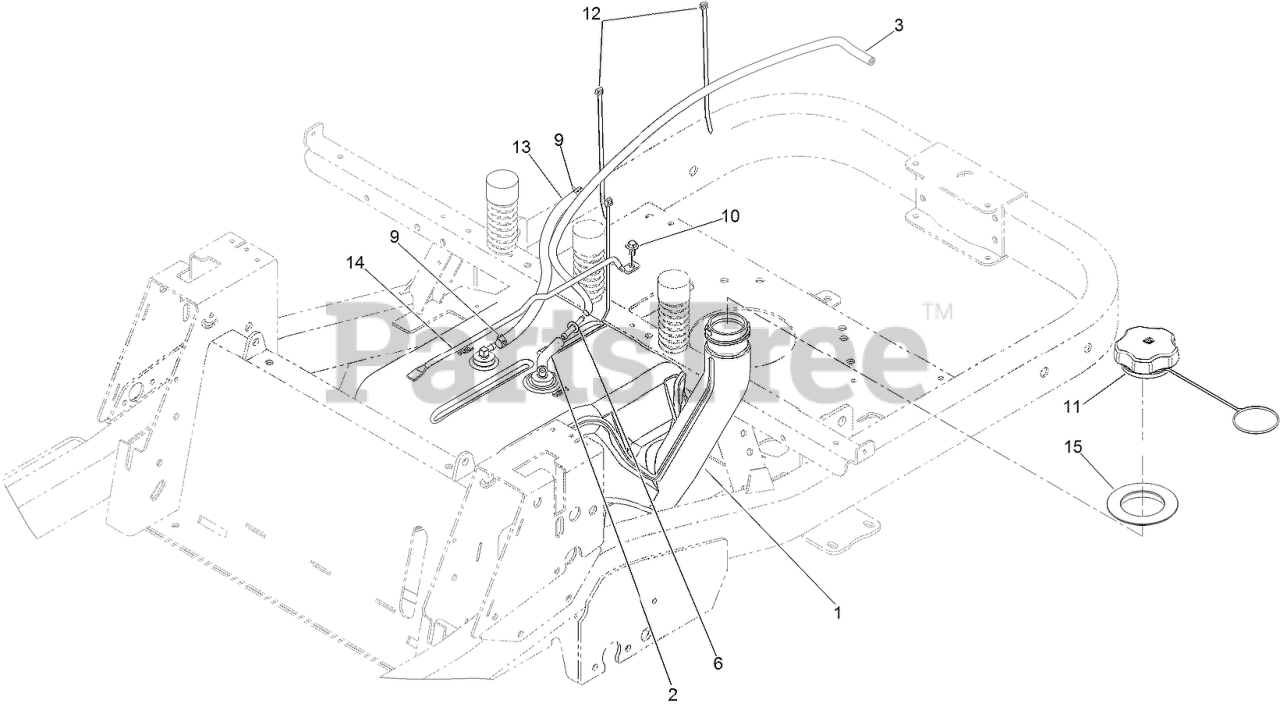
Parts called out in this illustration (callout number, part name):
1	FUEL TANK ASM
2	HOSE-FUEL
3	HOSE-FUEL
6	ADAPTER-ORIFICE
9	CLAMP-HOSE
10	SCREW-HHFTF
11	CAP-FUEL
12	TIE-CABLE
13	HOSE-FUEL
14	ROD-TANK, GAS
15	SEAL-TANK
